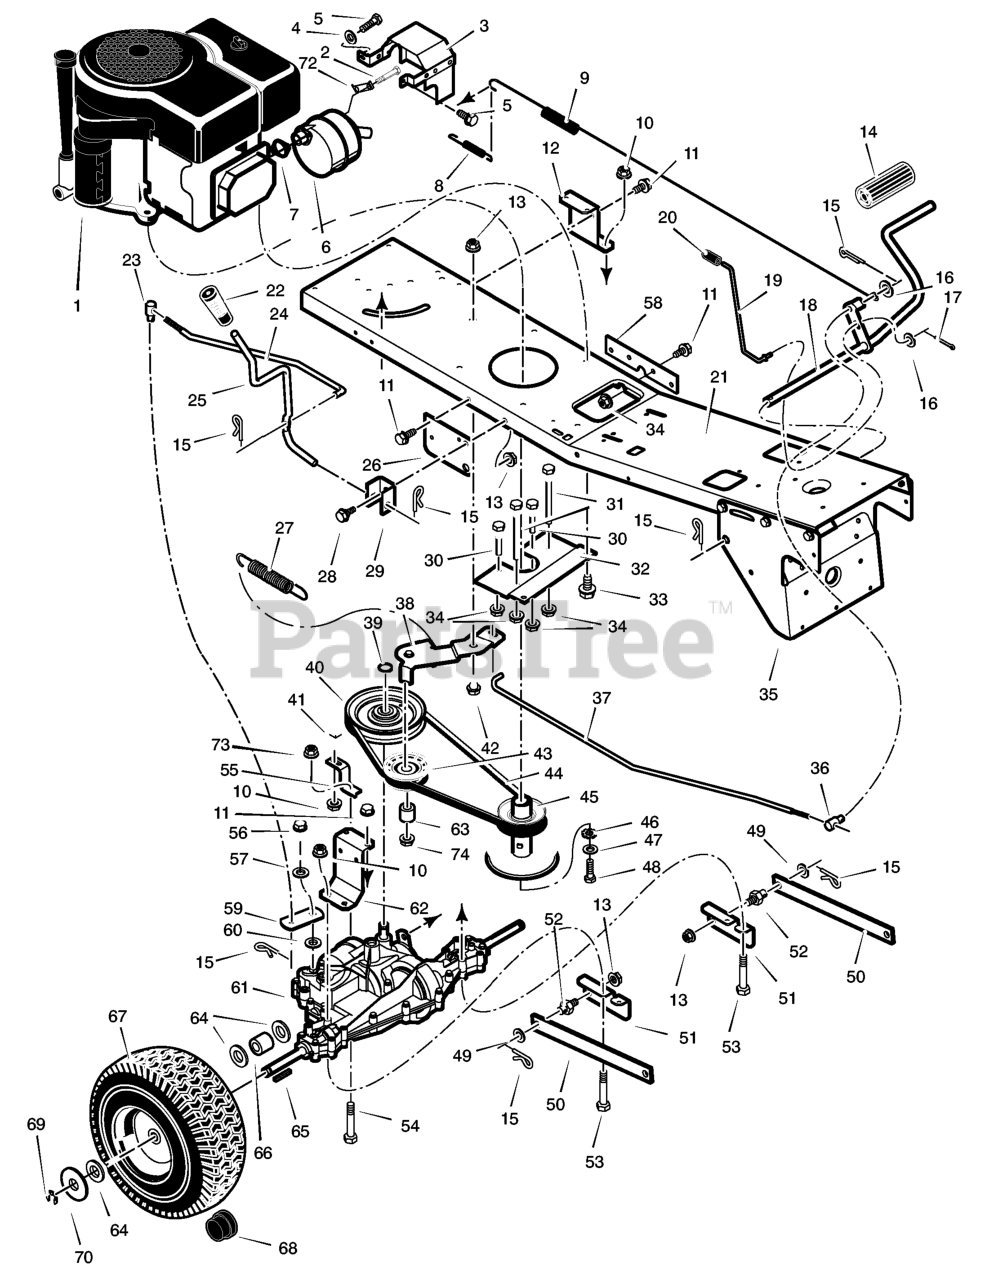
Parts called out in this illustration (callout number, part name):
1	Engine, Briggs & Stratton
2	Bolt, Hex
3	Shield Assembly, Heat
4	Lockwasher
5	Screw
6	Muffler
7	GASKET, Exhaust
8	Spring, Extension
9	Spring, Extension
10	Nut
12	Bracket, Left Transaxle
13	Nut, Flange
14	Cover, Pedal
15	Pin, Cotter
16	Washer
17	Pin, Cotter
18	Pedal Assembly
19	Rod, Parking Brake
20	Grip, Parking Brake Rod
22	Grip, Shift Lever
23	Nut, Adjusting
24	Link, Shift
25	Lever, Shift
26	Bracket, Lift Pivot
27	Spring, Extension
28	Bolt, Shoulder
29	Bracket, Pivot
30	Guide, Belt -Short
31	Guide, Belt -Long
32	Plate, Belt Guide
33	Bolt
34	Nut, Flange
35	Bracket, Support
36	Nut, Adjusting
37	Rod, Clutch
38	Clutch Arm Assembly
39	Ring, Retainer
40	Pulley, Drive
41	Bolt, Carriage
42	Bolt, Shoulder
43	Pulley, Idler
44	Belt, Motion Drive
45	Pulley, Split Stack
46	Washer, Star
48	Bolt, Hex
49	Washer
51	Bracket, Rear Hanger
52	Pin, Threaded Shoulder
53	Bolt, Hex
55	Bracket, Torque Reactor
57	Washer, Shift Yoke
58	Plate, Reinforcement
59	Yoke, Shift
61	Transaxle, Peerless **
62	Bracket, Right Transaxle
65	Key, Square
66	SPACER, Rear Wheel
67	Wheel, Rear -15"
68	Cap, Hub
72	Lock, Screw
73	Nut
74	Nut
